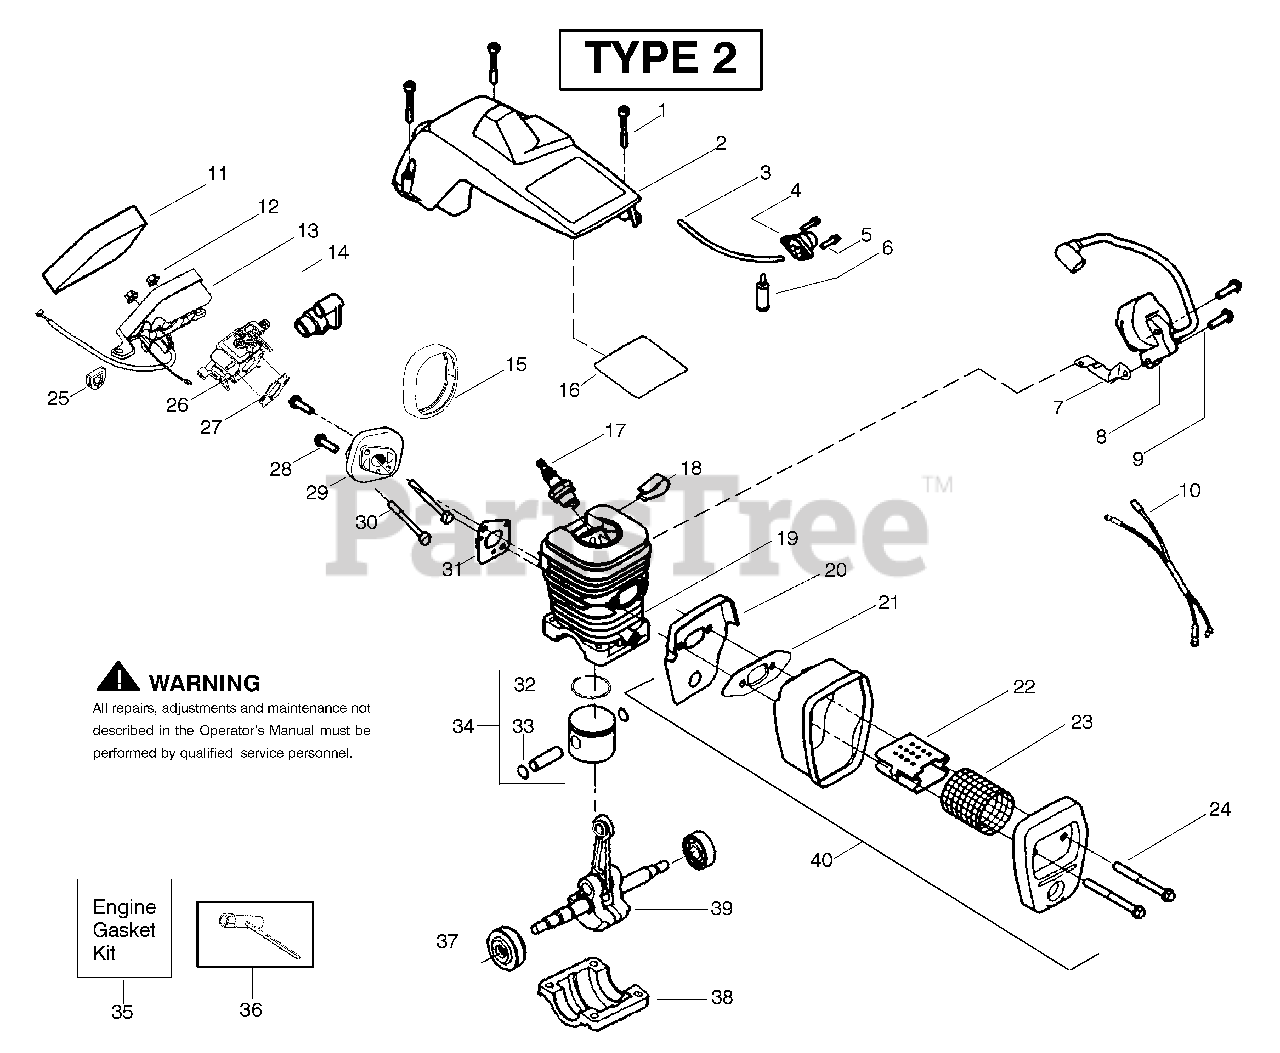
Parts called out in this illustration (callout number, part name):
2	Assy-Cylinder Shield
3	Kit-Fuel Line
4	Kit-Purge Bulb
6	Assy-Fuel Pick-Up
7	Strap-Ground
8	Ignition Module
10	Assy-Wire Harness
11	Foam- Air Filter
13	Assy- Air Box
14	Grommet-Carb Adjust
15	Seal-Carb Adapter
16	Reflector-Heat
17	Spark Plug
18	Clip-High Tension Lead
19	Cylinder
20	Backplate-Muffler
21	Gasket-Muffler
22	Diffuser-Muffler
23	Screen-Spark
24	Bolt-Muffler
25	Grommet-Throttle Cable
26	Kit-Carburetor Walbro (WT-89)
27	Gasket-Carb.
29	Carb. Adapter
31	Gasket- Adaptor
32	Ring-Piston
33	Retainer-Piston Pin
34	Kit-Piston
35	Kit-Engine Gasket
36	Wrench-Bar
37	Assy-Seal & Bearing
38	Cap-Crankcase
39	Assy-Crankshaft
40	Assy-Muffler
